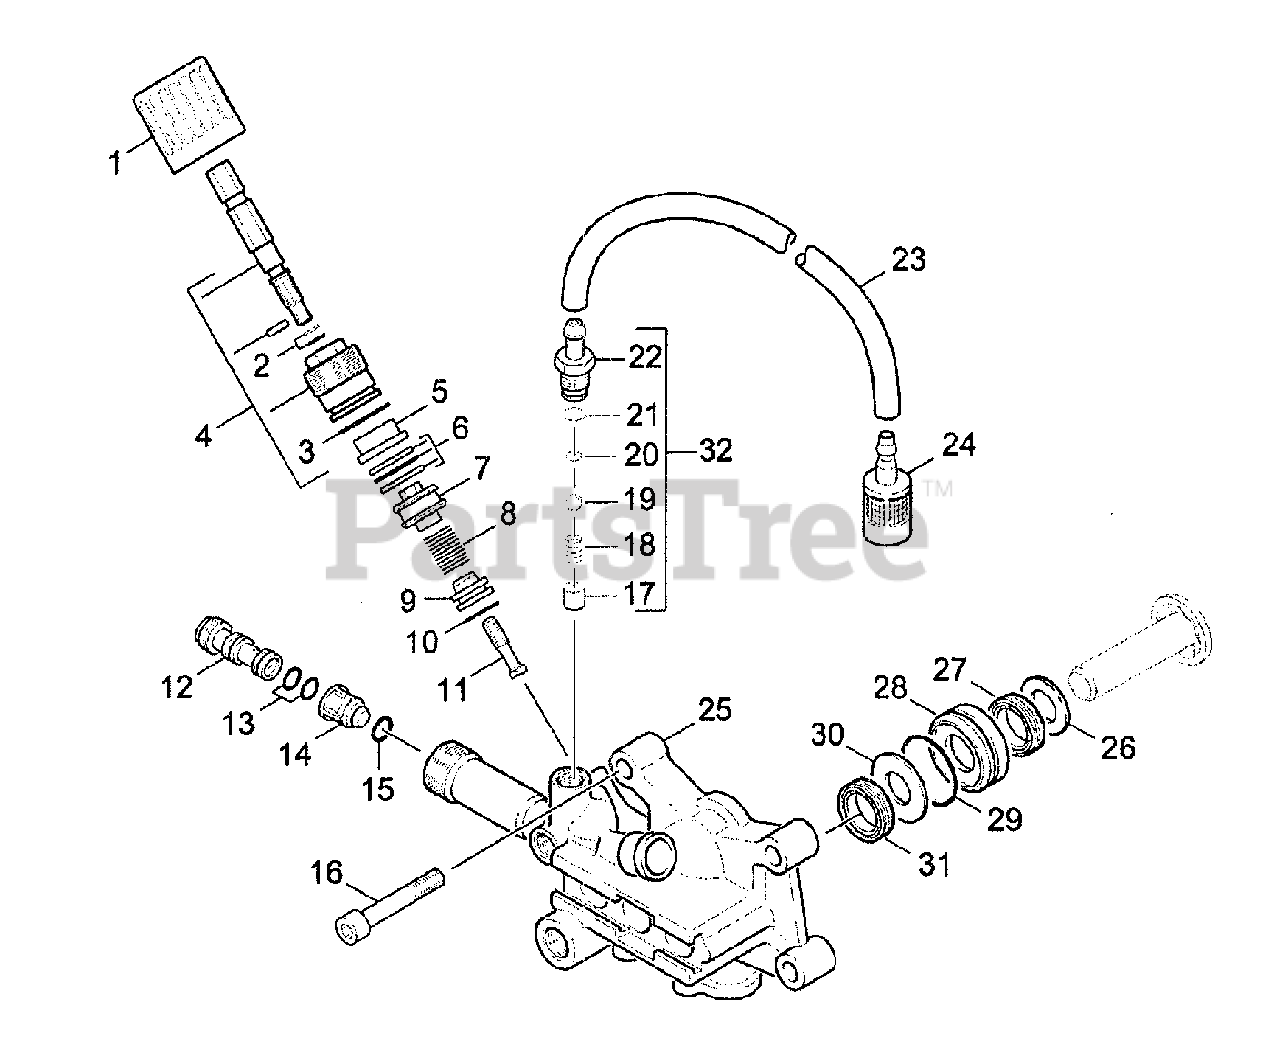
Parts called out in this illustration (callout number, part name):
4	Screw Union
8	Helical Spring
12	Nozzle Insert
18	Helical Spring
25	Cylinder Head
27	Grooved Ring
32	Rebuild Kit
